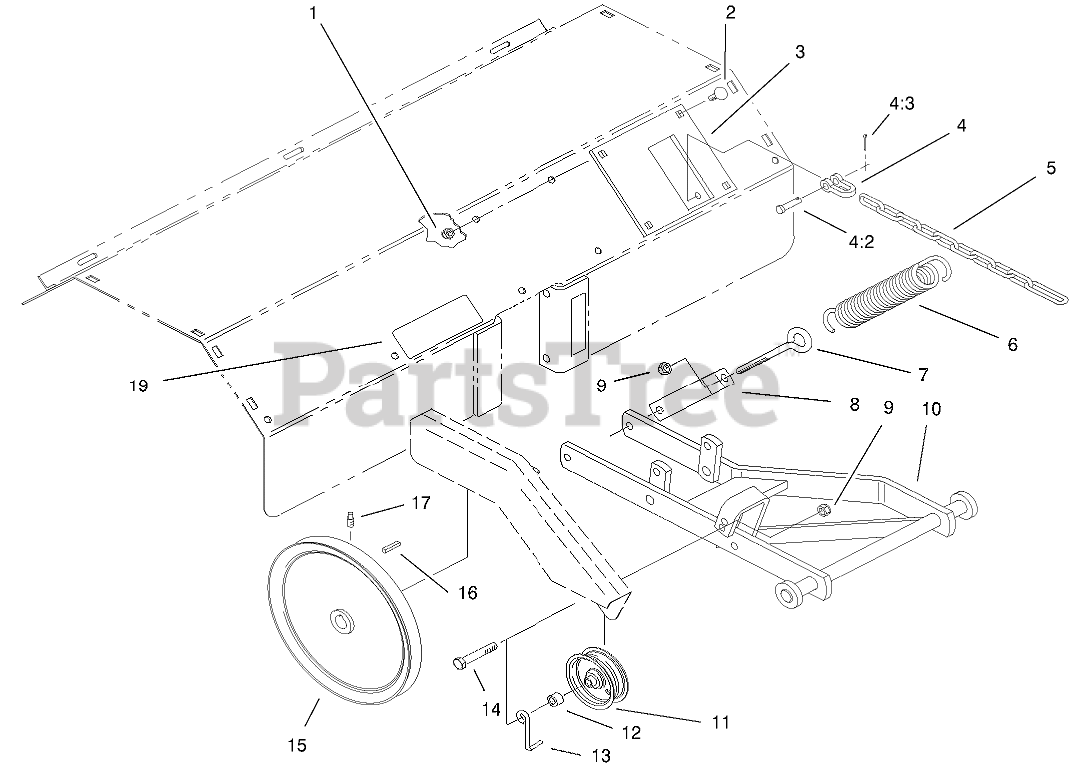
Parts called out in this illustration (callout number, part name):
1	NUT-LOCK, NI
2	BOLT-CARR
3	HITCH ASM
4	CLEVIS ASM
4:2	Clevis Pin
4:3	PIN-COTTER
5	CHAIN-LIFT
6	SPRING
7	EYEBOLT
8	BRACKET-SPRING
9	NUT-LOCK, NI
10	HITCH ASM
11	PULLEY-IDLER
12	Spacer
13	GUIDE-BELT
14	SCREW-HH
15	PULLEY
16	KEY-STRAIGHT
17	SCREW-SQH
19	DECAL-BELT ROUTING
